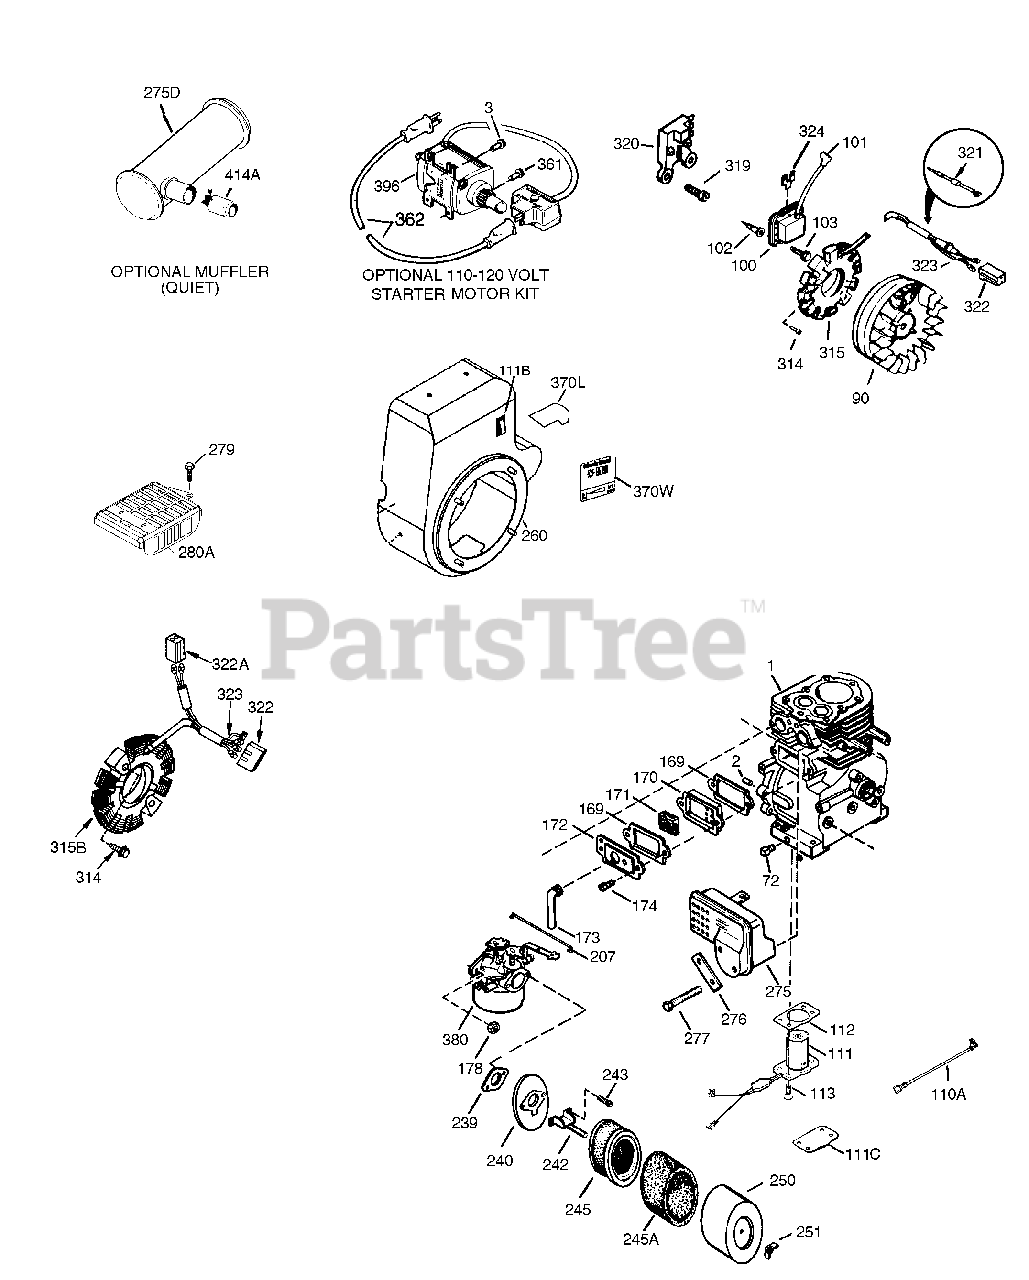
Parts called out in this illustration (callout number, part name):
1	"Cylinder (Incl. 2 & 20)
2	Dowel Pin
72	Oil Drain Plug (Sq. hd., 1/4-18)
90	Flywheel
100	Solid State Ignition
101	Spark Plug Cover
102	Solid State Mounting Stud
103	Screw, Torx T-15, 10-24 x 15/16"
110A	Ground Wire - Black, 13.25''
111	Low Oil Shut-Down Switch (Incl. 112)
111B	Rocker On/Off Switch
112	Low Oil Sensor Gasket
113	Screw, Torx T-25, 10-24 x 5/8"
130C	Screw, 5/16-18 x 5/8"
169	* Breather Gasket
170	Breather Body
171	Breather Element
172	Valve Cover
173	Breather Tube
174	Screw, 10-24 x 1/2"
178	Nut & Lock Washer 1/4-28
207	Throttle Link
238	Screw, 10-32 x 1/2"
239	* Air Cleaner Gasket
240	Air Filter Bracket
242	Air Cleaner Bracket
245	Air Filter (Paper) also available in Packaged Part #740027B
250	Air Cleaner Cover
251	Wing Nut, 1/4-20
260	Blower Housing
275	Muffler
276	Locking Plate
277	Screw, 5/16-18 x 3-3/16"
310A	Dipstick
370L	Low Oil Decal
380	Carburetor (Incl. 184)
702	Screw, 5/16-18 x 1-3/4"
